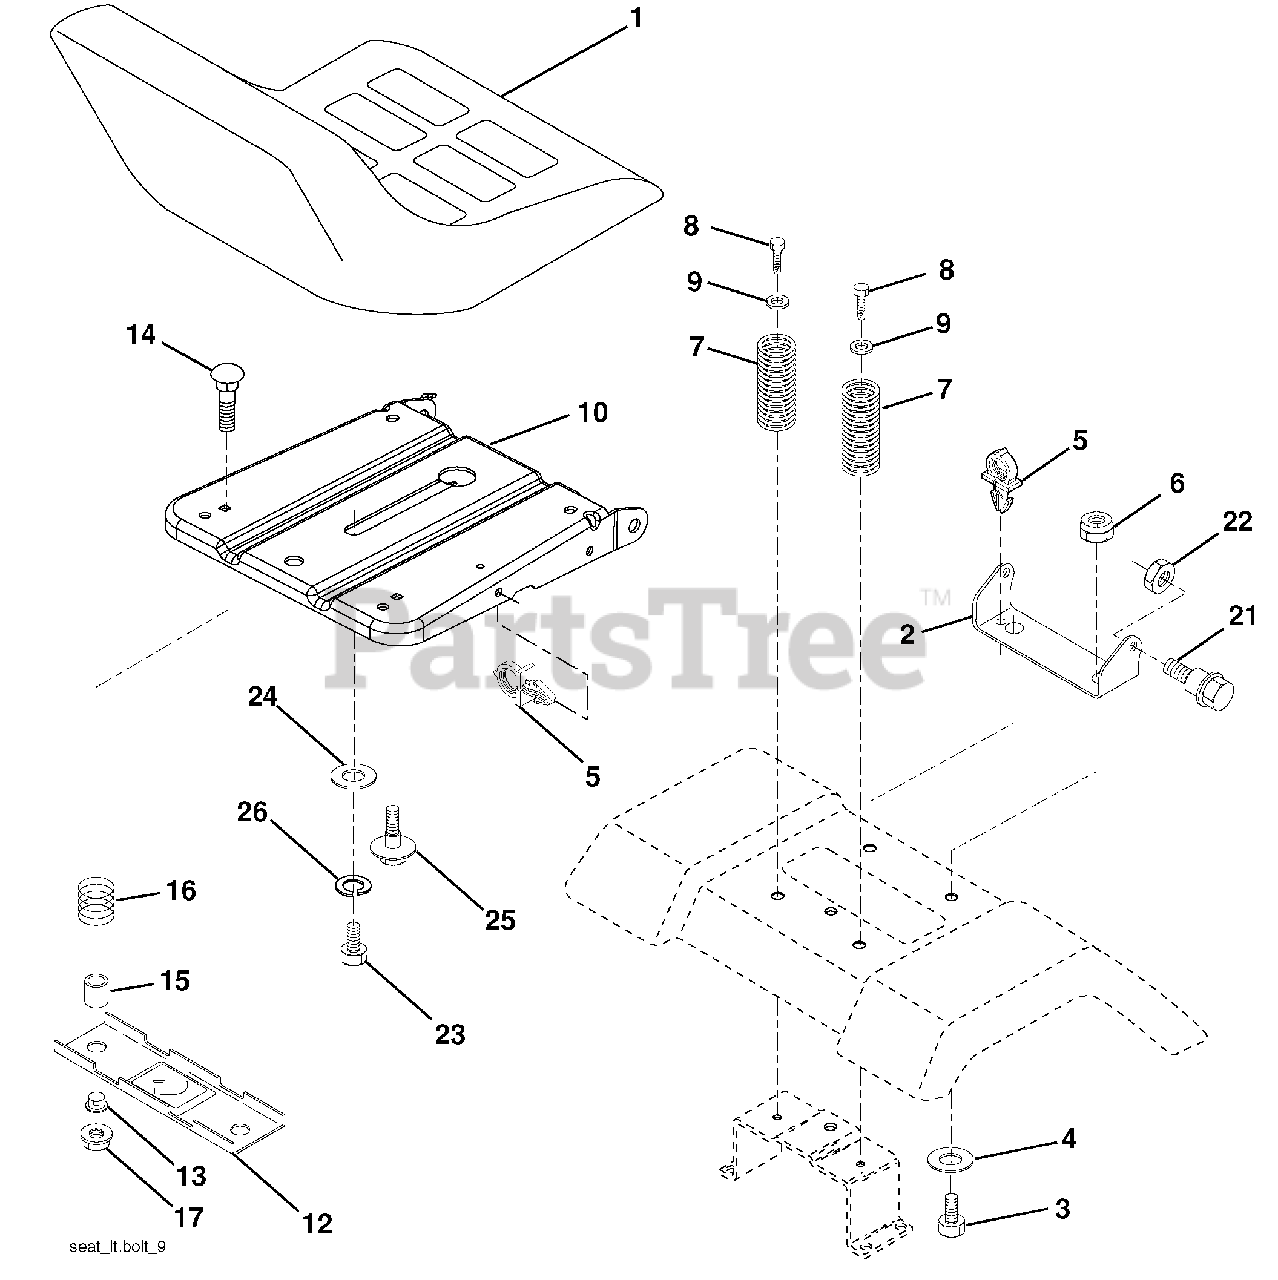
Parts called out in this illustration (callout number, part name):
1	Seat
2	Bracket Seat Pivot
3	Bolt Hex 3/8 - 16 x 1
4	Washer 13/32 x 1 x10 Ga.
5	Clip Push-In Hinged
6	Nut Lock Hex w/Ins 3/8 - 16
7	Spring Seat Cprsn 2 250 Blk
8	Screw 3/8-16 x 1.5
9	Washer 13/32 x 1 x 14 Ga.
10	Pan Asm. Seat
12	Bracket Pnt Mounting Switch
13	Bushing Snap Blk Nyl
14	Bolt Rdhd Sht Nk 1/4 - 20 x 1 -1/2
15	Spacer Split .28 x .96
16	Spring Cprsn
17	Nut Lock 1/4 Lge Flg
21	Bolt Shoul der 5/16-18 unc-2A
22	Nut Lock Hex w/Ins 5/16 - 18
23	Bolt Hex
24	Washer 17/32 x 1-3/16 x 12 Ga.
25	Bolt Shoul der 5/16-18 x .62
26	Washer Lock Hvy Hlcl Spr 1/2
